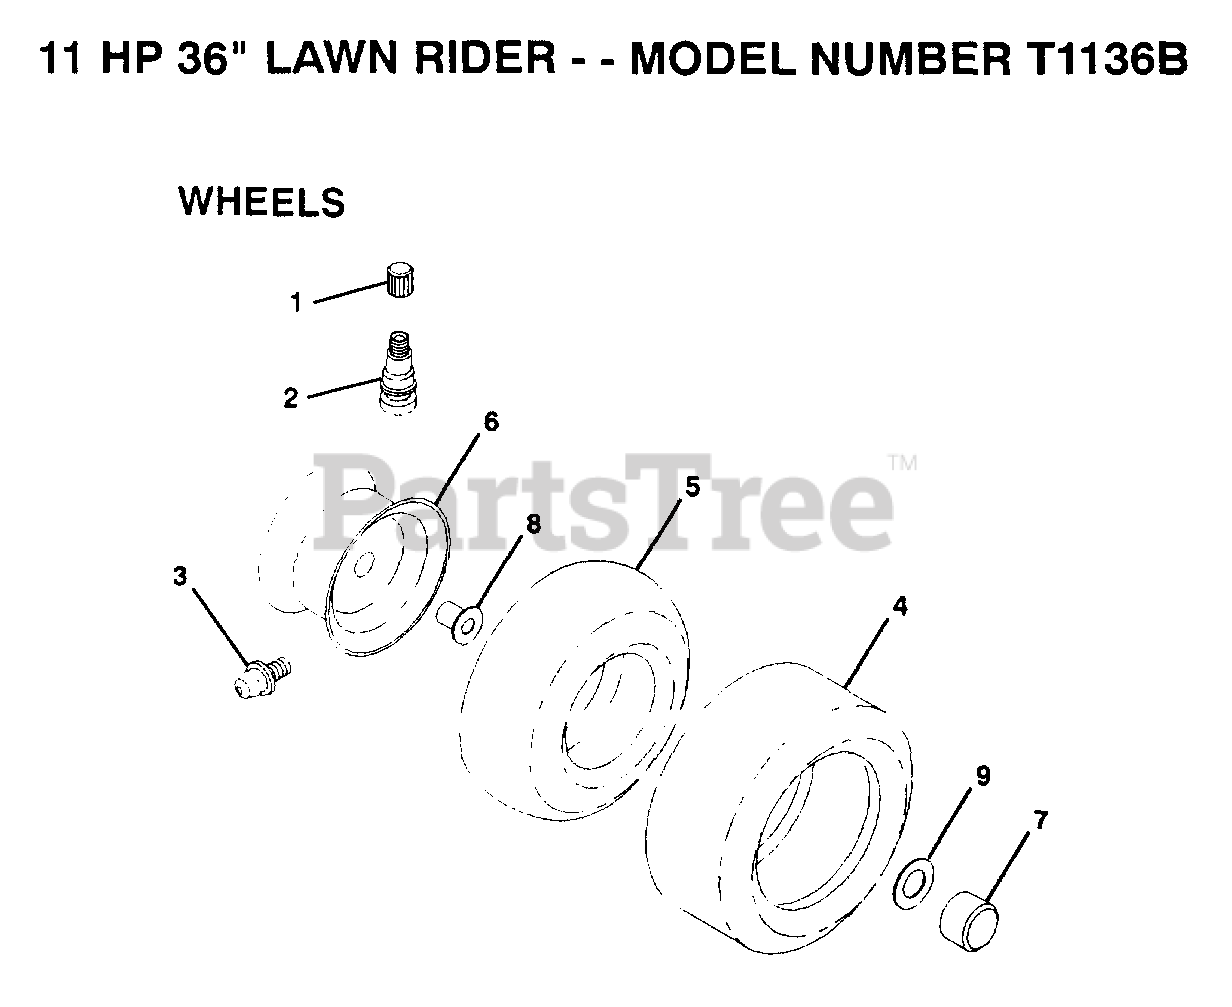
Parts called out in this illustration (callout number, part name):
1	VALVE CAP
2	VALVE STEM LT
3	FITTING LT
5	TUBE.5.3/4.5/6
7	HUB CAP
8	"FLANGE, BEARING"
9	WASHER
